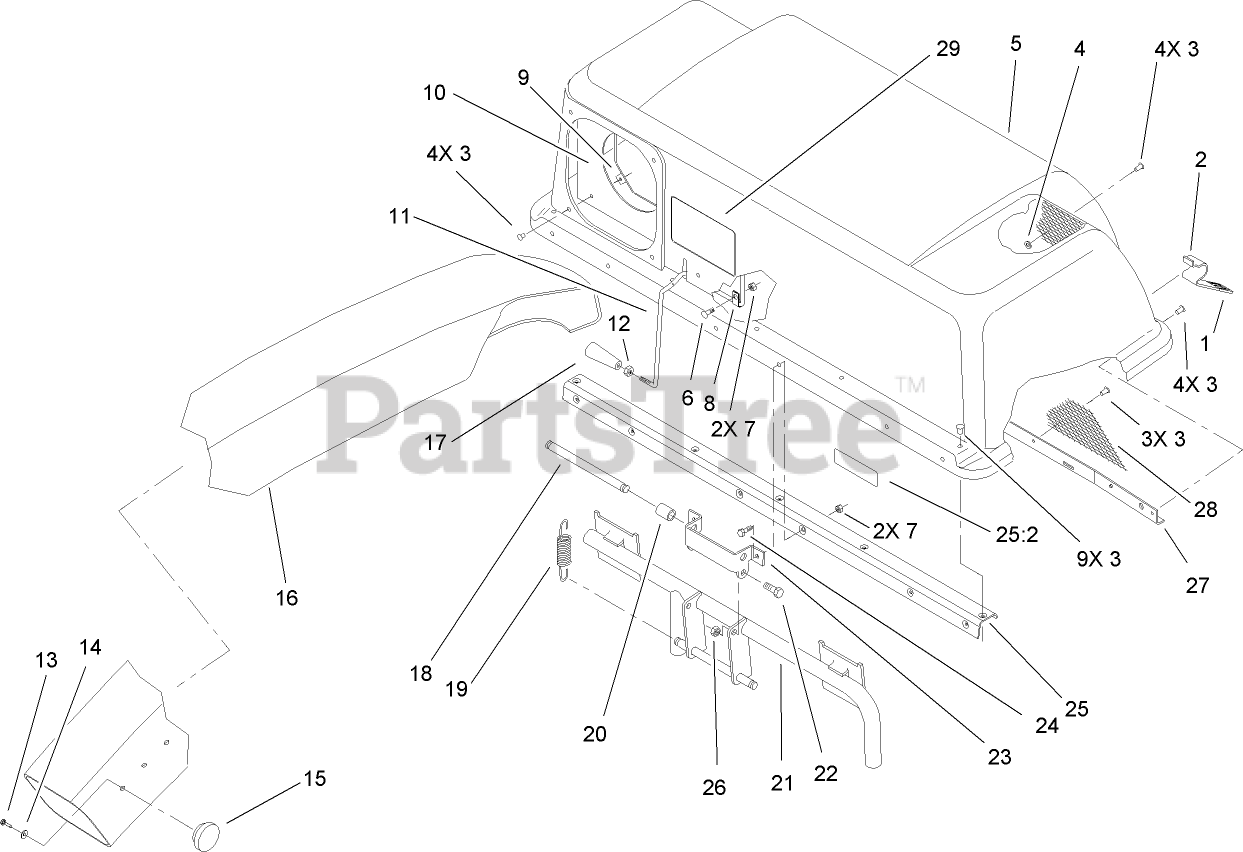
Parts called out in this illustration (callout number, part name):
2	LATCH-BAGGER, TOP
3	RIVET-BLIND
4	WASHER-FLAT
5	TOP-BAGGER
6	SCREW-PPH
7	NUT-LOCK, NI
8	CLAMP
9	CLAMP-SEAL
10	SEAL-CHUTE
11	FEELER-FILL, BAG
12	NUT-JAM
13	SCREW-PPHTF
14	WASHER-PLAIN
16	CHUTE-DISCHARGE
17	HANDLE-TAPERED
18	PIN-SPRING
19	SPRING-EXTENSION
20	SPACER
21	FRAME ASM
22	SCREW-HH
23	HINGE-BAG, TOP
24	SCREW-HH
25	STIFFENER ASM
25:2	DECAL-CAUTION
26	NUT-LOCK, NI
27	SUPPORT-SCREEN
28	SCREEN-BAGGER
29	DECAL
